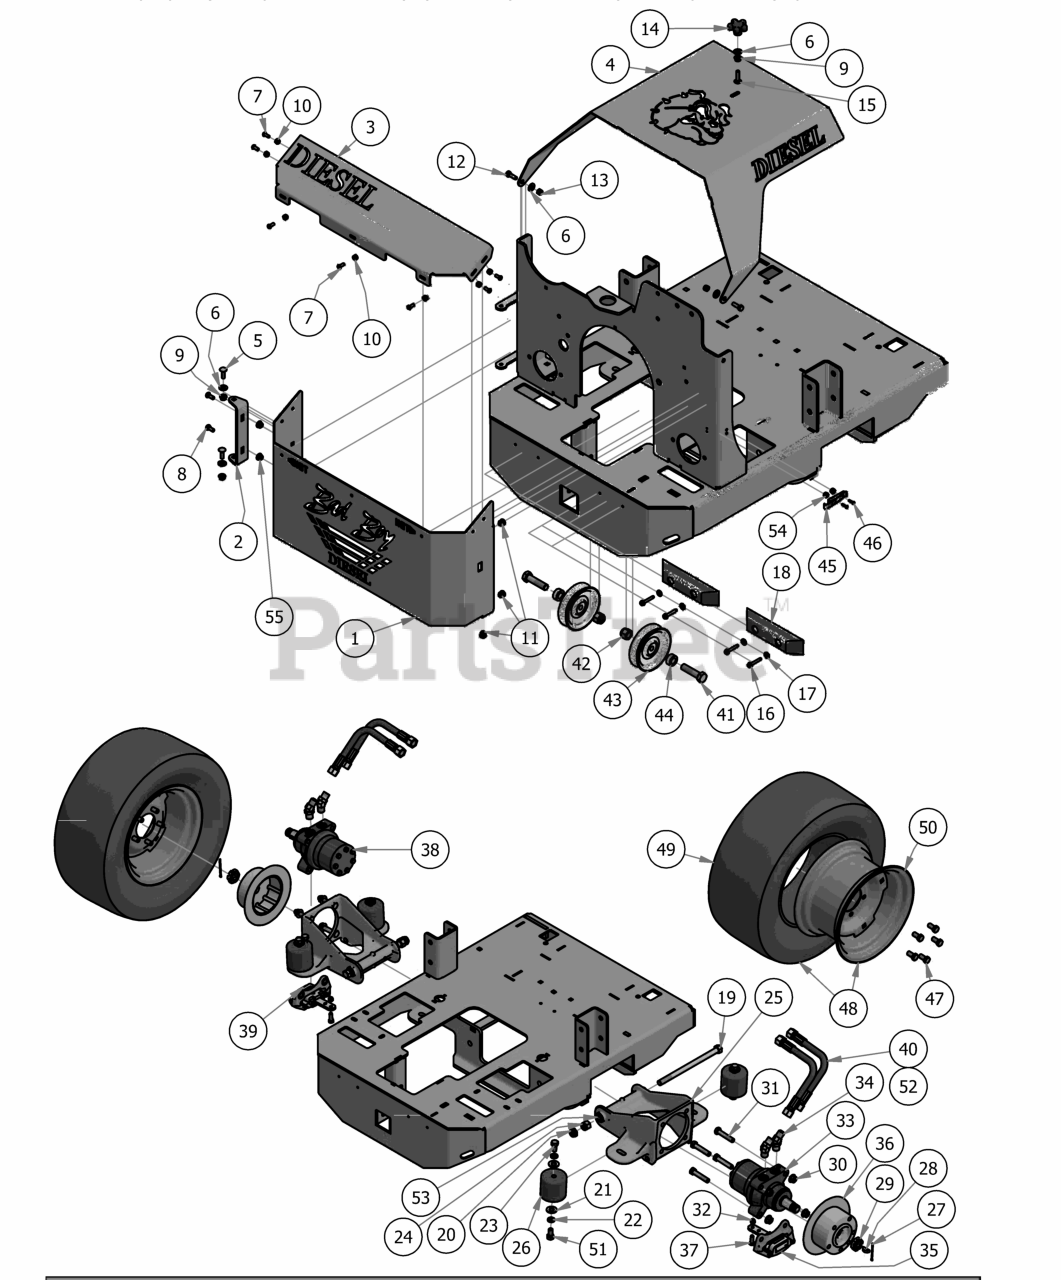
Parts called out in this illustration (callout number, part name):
1	Diesel Back Pump Cover 2008 Bottom
2	Back Cover Hinge Bracket
3	Diesel Back Pump Cover 2008 Top
4	Diesel Hood 3 Cyl
5	5/16" x 1" Carriage Bolt
6	.360 ID Plastic Washer
7	1/4" x 5/8" BS C/S 18-8 SS
8	5/16-18x3/4 carriage bolt
9	5/16" Flange Nut
10	1/4 Nylock Nut
11	5/8 Round Insert
12	5/16" x 1" Bolt
13	5/16-18 Nylock Insert Locknut
14	5/16" Knob
15	5/16" x 1 1/4" Carriage Bolt
16	1/4" x 1 1/2" Self Tapping Screw
17	1/4" Flat Washer
18	8" Rubber Bumper
19	5/8''x10'' Hex Bolt (Grade8)
20	5/8" Nylock (1/2 Jam)
21	1/2" Washer (Grade 8)
22	1/2" Lock Washer
23	1/2" x 1" Hex Bolt
24	5/8 Std NC Nylock Nut
25	60 Suspension kit Wheel Motor
26	Vibration Mount-Blue Dot
27	1/8x2-1/4 cotter pin Zinc
28	Woodruff Key
29	1" Castle Nut for Wheel Motor
30	1/2" Flange Nut
31	1/2" x 2 1/2" Hex Bolt
32	5/16-18 Nylock Insert Locknut
33	18cc Parker Wheel Motor- Right
34	45 Degree Wheel Motor Fitting -6802-10-10
35	XP/AOS Right Brake Caliper
36	Brake Disk
37	3/8" x 1" Hex Bolt
38	18cc Parker Wheel Motor- Left
39	XP/AOS Left Brake Caliper
40	26" Hose Assembly with Adaptors
41	5/8" x 2 1/2" Grade 5 Hex Bolt (Coarse)
42	5/8 Std NC Nylock Nut
43	5 V Idler Pulley - BCVI- 81
44	5/8" x 1/" Collar W/One Set Screw
45	Steel Pump Cover Latch
46	10-24 X 5/8 BS Button Head Bolt
47	1/2" x 1" Hex Bolt
48	26 x 12.00 - 12 Tire and Orange Wheel Assembly
49	26 x 12.00 - 12 Tire
50	12 x 10.5 Wheel AOS Rear
51	1/2-13 1-1/4 Hex bolt
52	26" Hose Only
53	Brass Bushing
54	10-24 Nylock Locknut
55	5/16" Nylon Flange Nut
